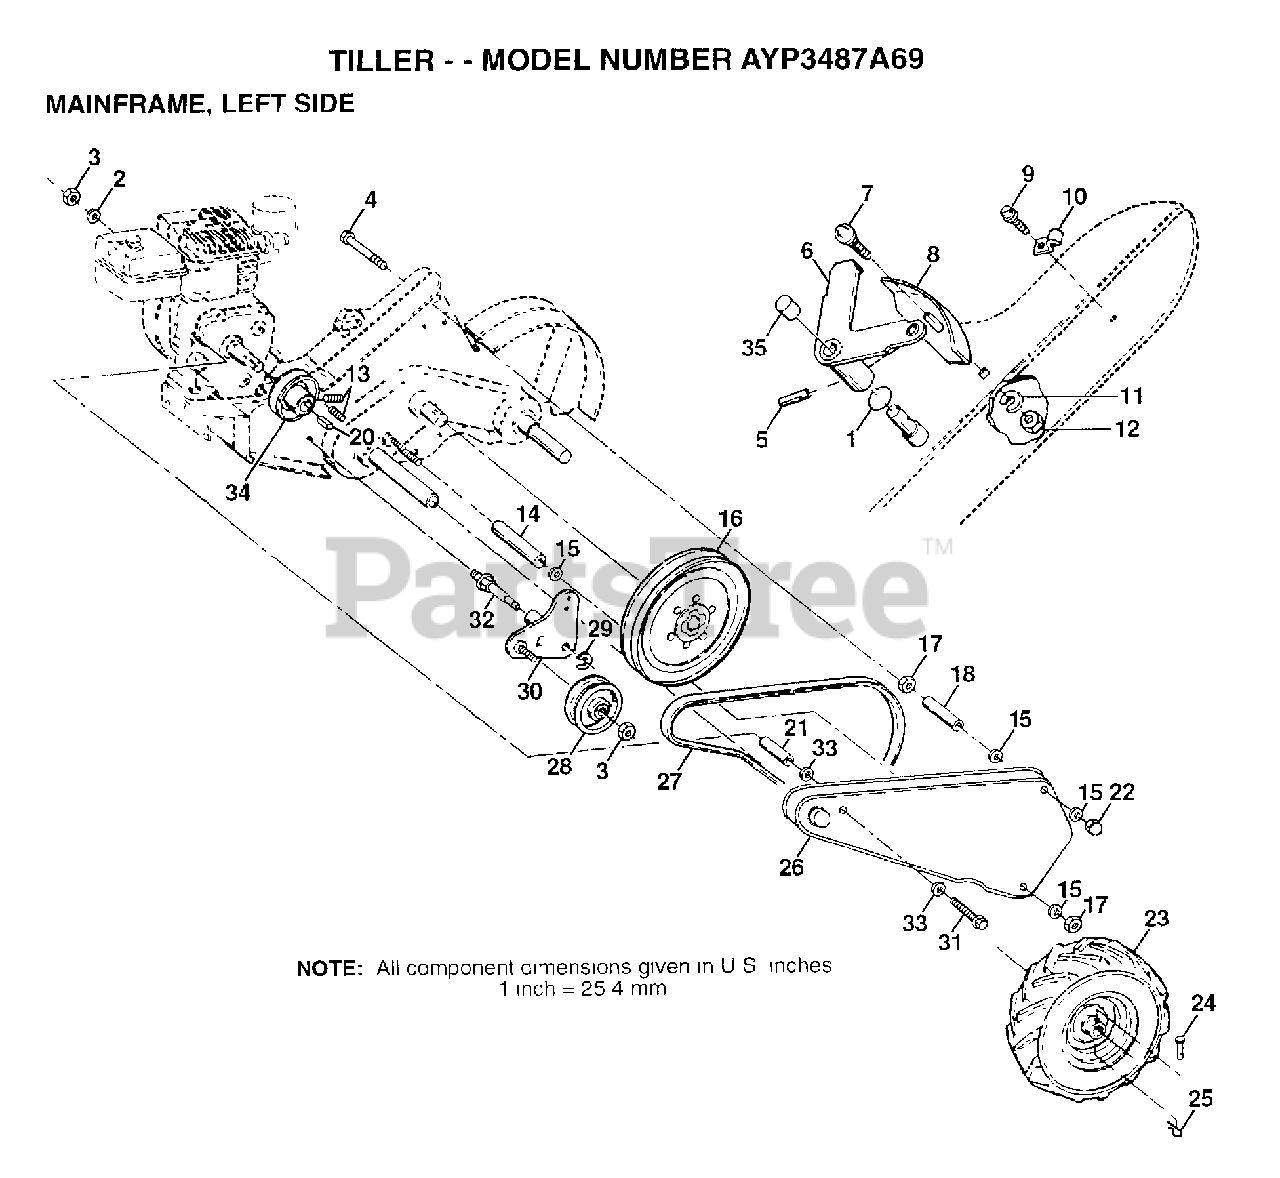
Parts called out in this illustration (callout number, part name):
1	O-RING TI
2	LOCKWASHER
3	NUT.HEX.3/8-16UNC
4	BOLT TI
6	LEVER ASM CRT
7	BOLT
8	PANEL TI
10	CONDIUT CLIP T
11	LOCKWASHER
13	SET SCREW
14	SPACER TI
15	WASHER
16	SHEAVE.TRANS.
17	NUT.HEX.5/16-18
18	SPACER TI
20	KEY TI
21	SPACER.SPLIT
22	NUT TI
23	TIRE TI
24	RIVET.PAN HD.1.75
25	SPRING.RETAINER
26	GUARD BELT RED
27	BELT.DRIVE
29	KLIP RING
31	BOLT1/2-20UNF2.75
32	SHAFT.IDLER
34	SHEAVE CRT
35	CAP PLUNGER BLACK
